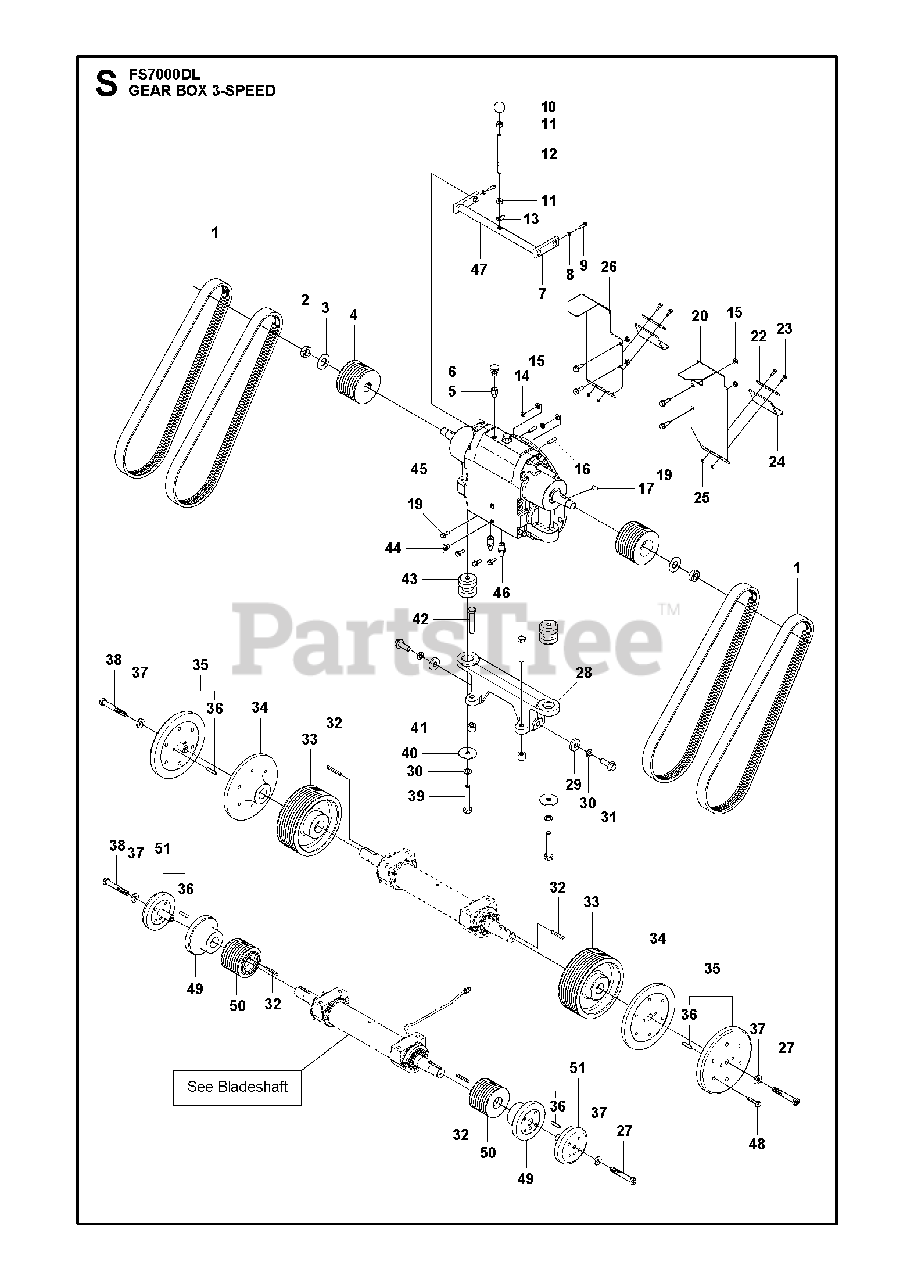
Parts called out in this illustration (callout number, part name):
15	WASHER
25	HEXAGON LOCKING NUT
27	SCREW26”, 30”, 36”
35	FLANGE60" Including Pin"
38	SCREW26”, 30”, 36”
43	ANTIVIBRATION ELEMENT
49	FLANGE26”, 30”
50	PULLEY26”, 30”
51	FLANGE36" Including Pin"
51	FLANGE42" Including Pin"
51	FLANGE48" Including Pin"
